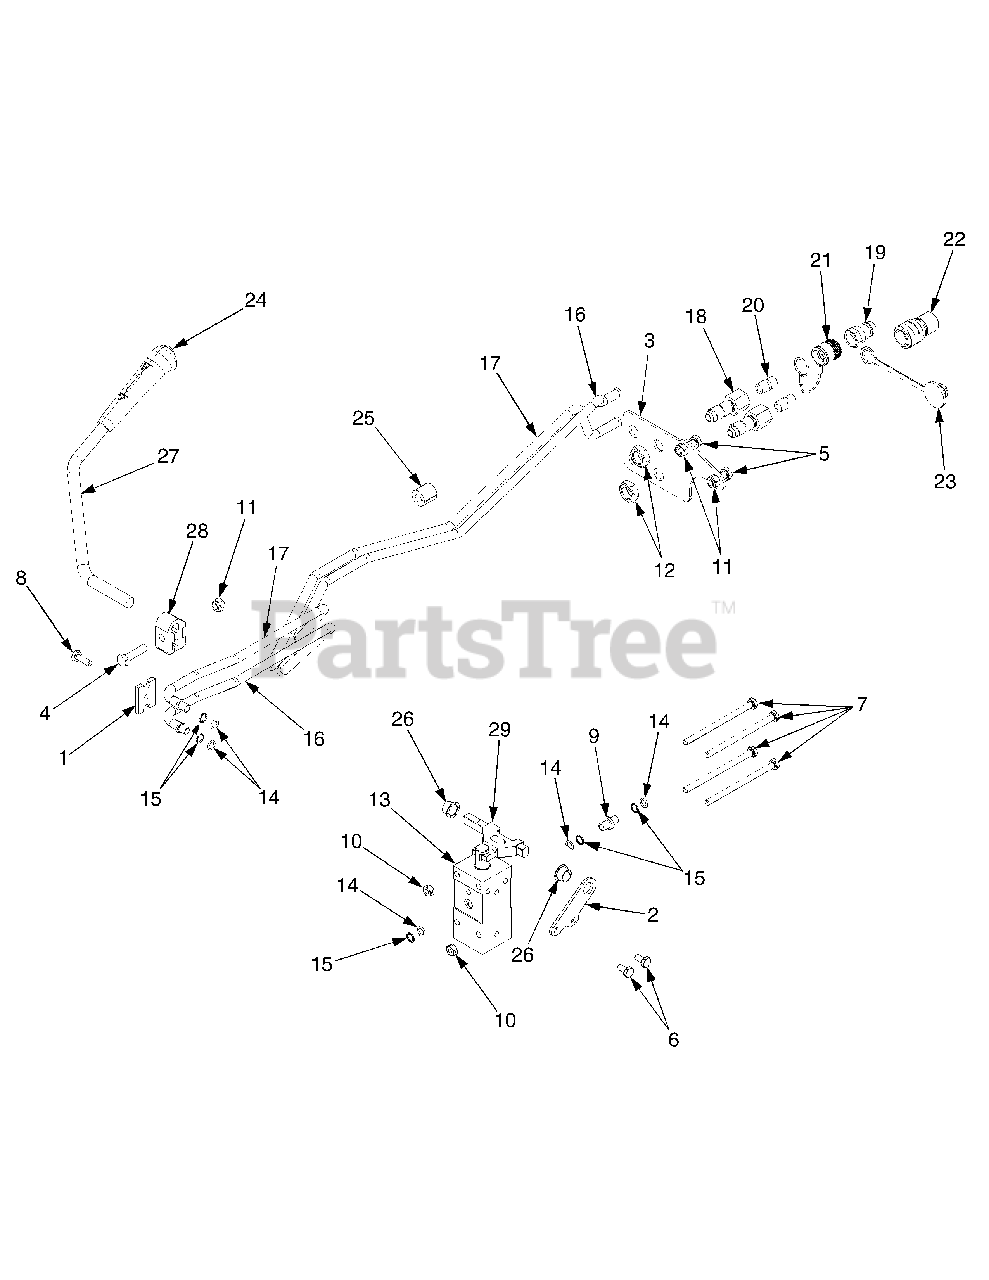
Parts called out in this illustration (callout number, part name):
1	Double Clamp
2	Valve Bracket
5	Hex Cap Scrw, 5/16-18 x .625 GR5
6	Hex Cap Screw, 1/4-20 x .5 GR5
7	Hex Cap Screw, 1/4-20 x 4.0
8	Hex Cap Scrw, 1/4-20 x .75 GR5
9	Union Fitting
10	Hex Lock Nut, 1/4-20
11	Hex Insert Lck Nut, 5/16-18 GR5
12	Hex Jam Nut. 9/16-18 GR5
13	Hydraulic Valve
14	O-Ring, .301 x .070
15	Backup O-Ring, .327 x .43 x .049
16	Hydraulic Tube,(Up)
17	Hydraulic Tube (Down)
18	Bulkhead Fitting
19	Hydraulic Coupling - Male
20	Fitting Nipple
21	Male Coupling Protective Cap
22	Hydraulic Coupling - Female
23	Female Coupling Protective Cap
25	Bumper Pad
26	Nylon Flange Bearing
27	Valve Handle
28	Handle Clamp
